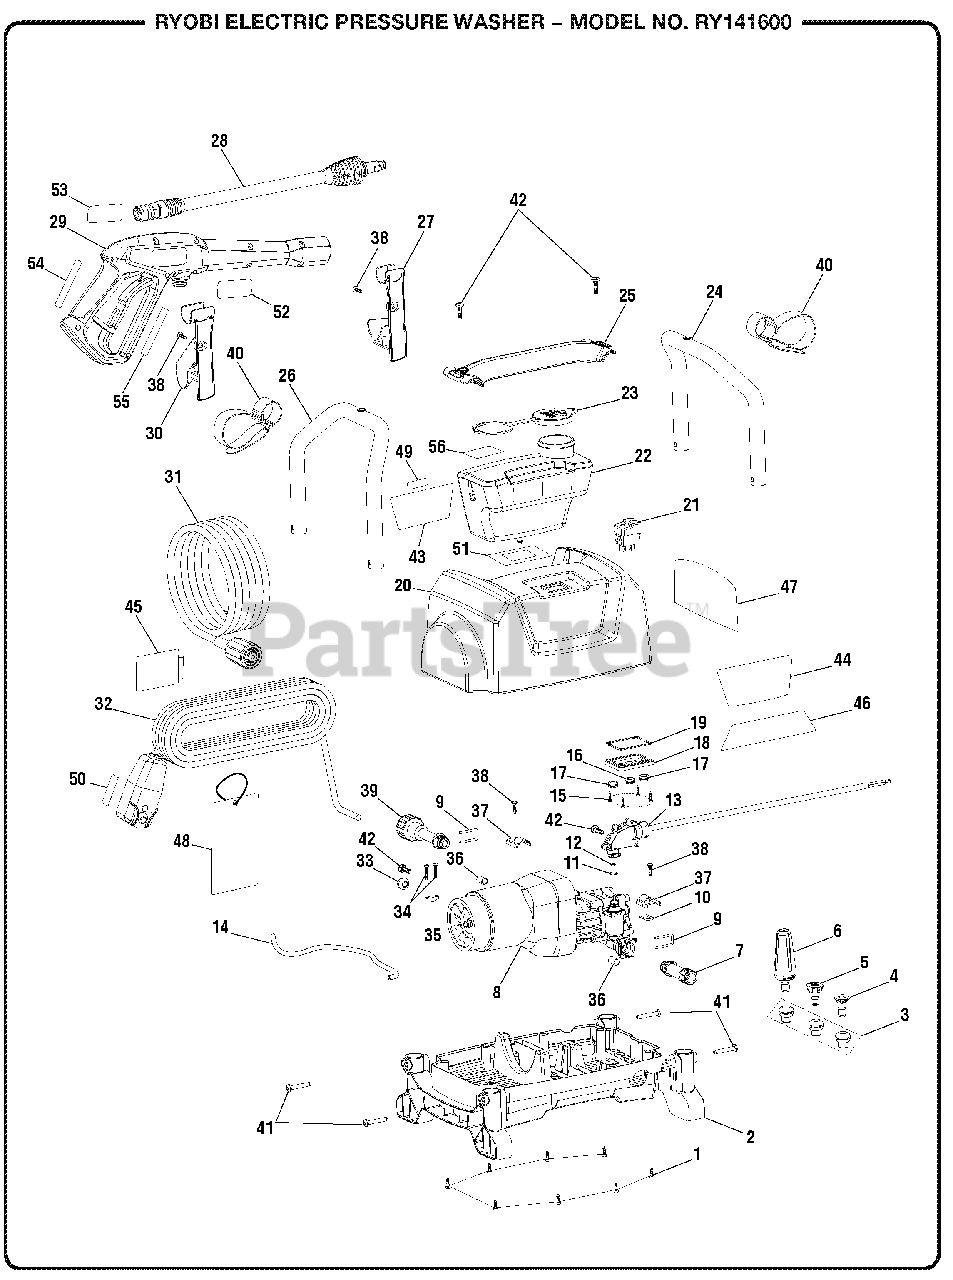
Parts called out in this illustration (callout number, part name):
1	Screw (M4 x 15 mm)
2	Lower Motor Housing
3	Nozzle Grommet
4	Soap Nozzle
5	15deg Nozzle
6	Turbo Nozzle
7	Outlet Tube Assembly
8	Motor and Pump Assembly
11	Washer (Brass)
12	O-Ring
13	Pressure Switch
14	Detergent Suction Hose
15	Screw (M3 x 14 mm)
18	Switch Cover
19	Switch Cover Gasket
20	Top Motor Housing
22	Detergent Tank Assembly
23	Detergent Tank Cap
24	Left Frame Assembly
25	Handle Assembly
26	Right Frame Assembly
27	Trigger Handle Holder (Left)
28	Spray Wand
29	Trigger Handle
30	Trigger Handle Holder (Right)
31	High Pressure Hose
32	Power Cord
34	Screw (M35 x 20 mm)
35	Cord Clamp
37	Motor Clamp Plate
38	Screw (M4 x 12 mm)
39	Inlet Tube Assembly
40	Hose Storage Strap
41	Bolt (M6 x 35 mm)
42	Bolt (M6 x 20 mm)
43	Quick Start Label
44	Ryobi Logo Label
45	Cord Wrap Label
46	Performance Label
47	Danger Label
48	Warning Hangtag
49	Inquires Label
50	Cord Plug Label
51	On/Off Switch Label
52	Trigger Handle Label
53	Trigger Handle Warning Label (English)
54	Trigger Handle Warning Label (French/Spanish)
55	Trigger Handle Rating Label
56	Detergent Tank Label
